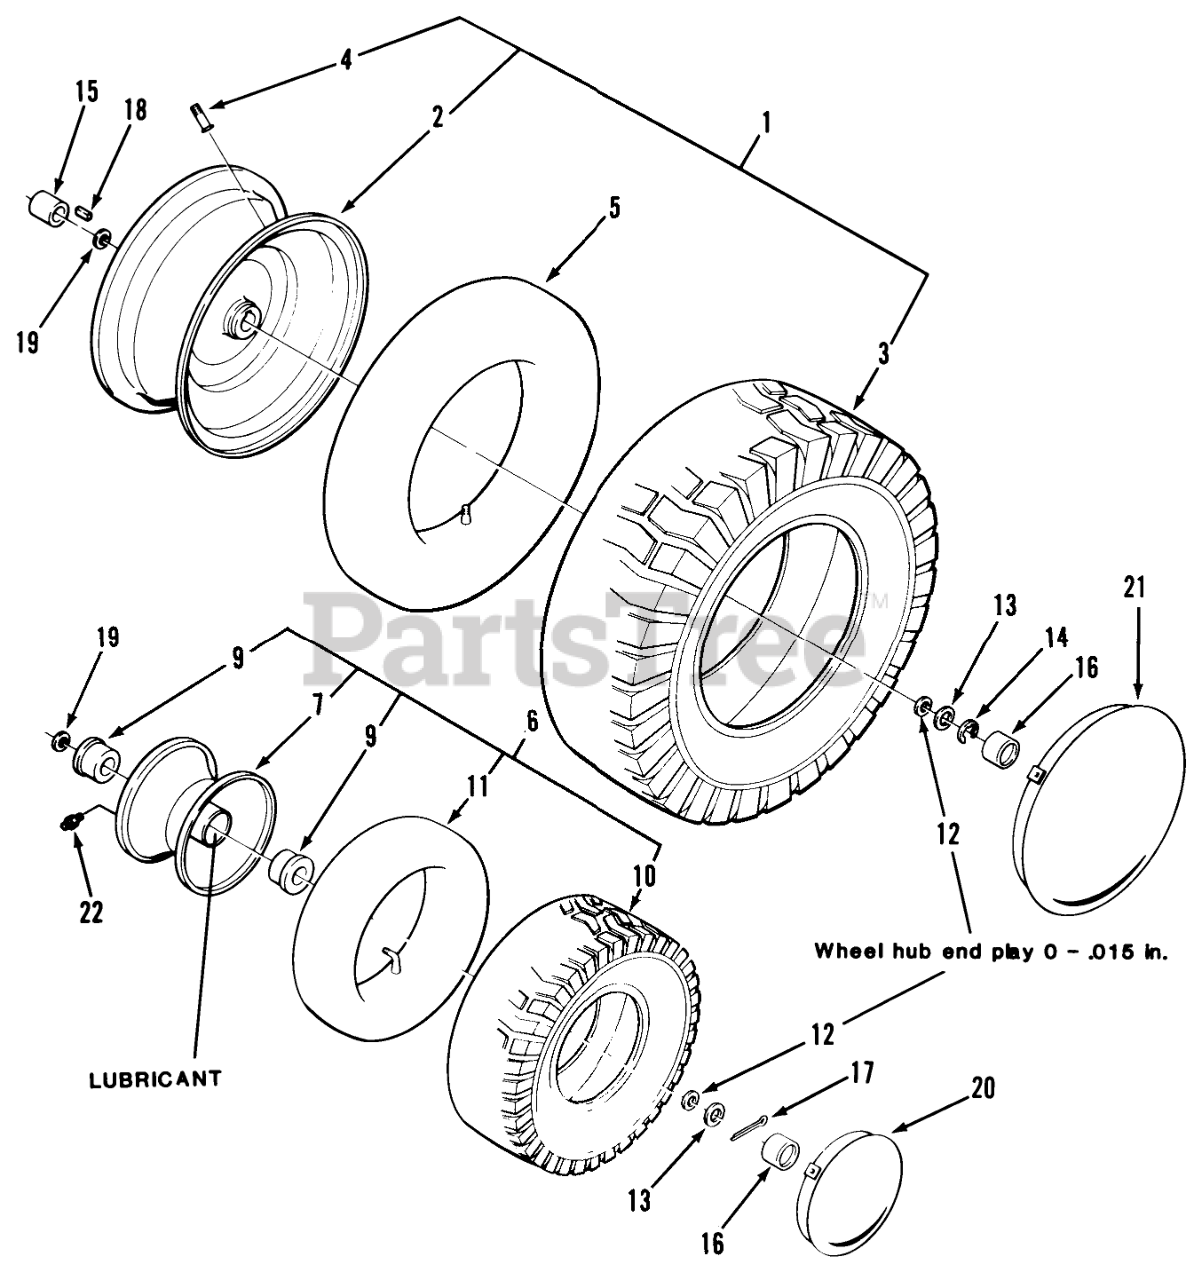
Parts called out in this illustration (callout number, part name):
1	Rear Wheel and Tire 108-3 Only
1	Rear Wheel and Tire 108-4 Only
1	Rear Wheel And Tire Assy 108-5, 111-5 Only
2	Rear Wheel 108-4 Only
2	ASSY WHEEL
3	Rear Tire 4.80 x 4.00-8 108-3 Only
3	Rear Tire 16 x 6.50-8 108-3 Only
3	TIRE TURF SAVER 16X6.50-8
4	VALVE
5	TUBE-INNER
6	Front Wheel and Tire 108-3 Only
6	ASSY WHEEL & TIRE
6	Front Wheel and Tire 11 1-5, 111-6 Only
7	Frt Wheel w/Bushings & Grease Fitting 108-4
7	ASSY WHEEL
9	BEARING-WHEEL
9	FLANGE BEARING
10	Tire 4.10 x 3.50-4 108-3 Only
10	Tire-Front 4-10 X 3.50-4
12	WASHER-FLAT
13	WASHER
14	E Ring
15	LH AXLE SPACER
16	HUB CAP-FLAT BLACK
16	HUB CAP
17	Cotter Pin
18	SQ KEY
19	WASHER-SHIM
20	Hub Cap 4" 111-5 Only
21	HUB CAP 8 IN
22	ZERK-GREASE
